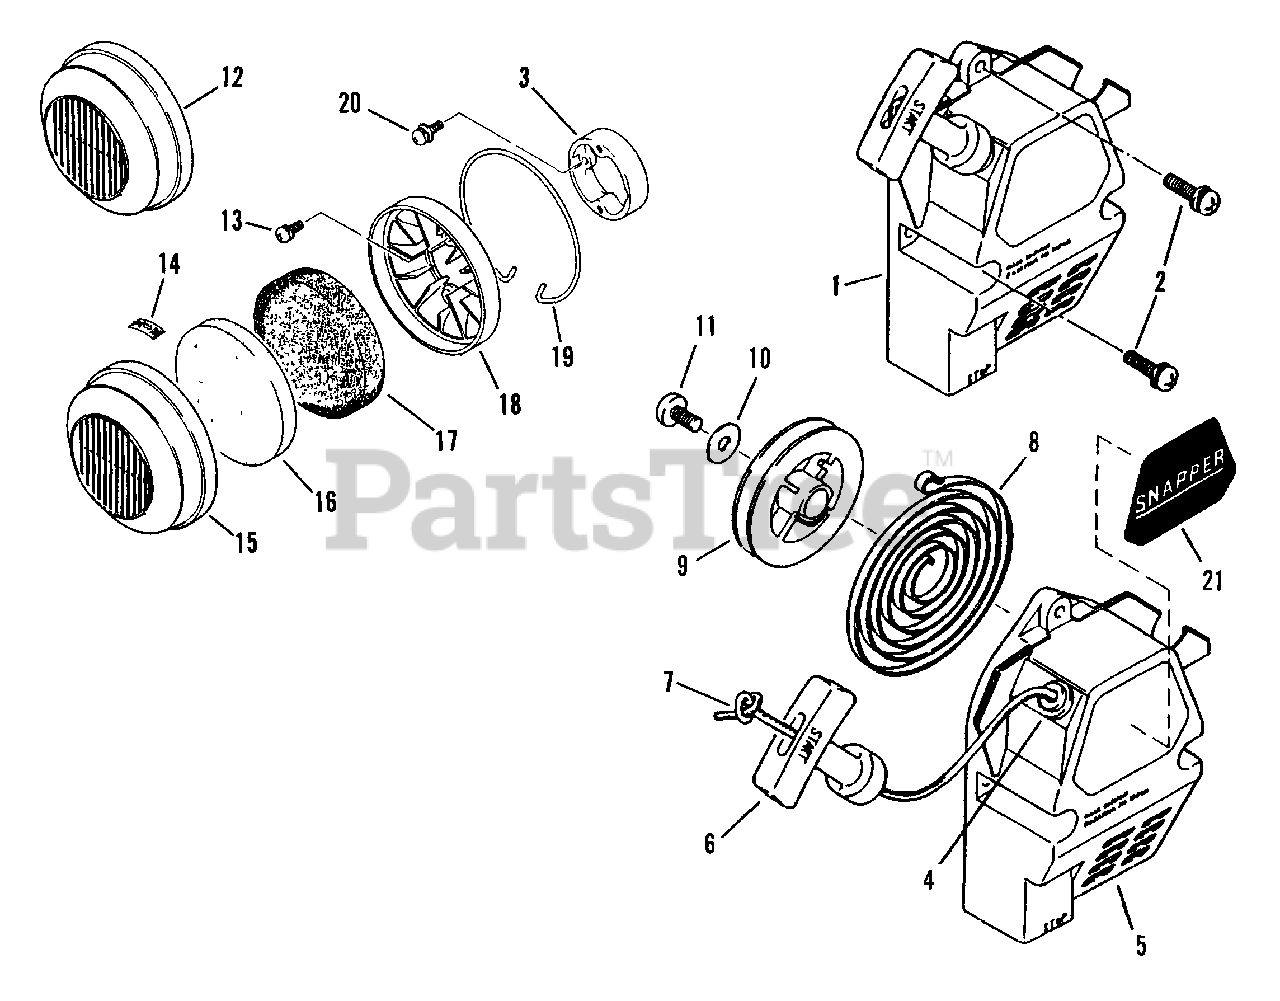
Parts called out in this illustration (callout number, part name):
1	RECOIL STARTER ASSM'Y.
2	SCREW/WASHER
5	HOUSING, Starter
6	KNOB, Starter
7	ROPE, Starter
8	SPRING, Spiral
12	ASSEMBLY, Air Cleaner
13	SCREW/WASHER
14	LABEL, Choke
15	COVER, Cleaner
16	ELEMENT, Cleaner
17	ELEMENT, Cleaner
18	CASE, Cleaner
20	SCREW/WASHER
21	LABEL, Snapper
